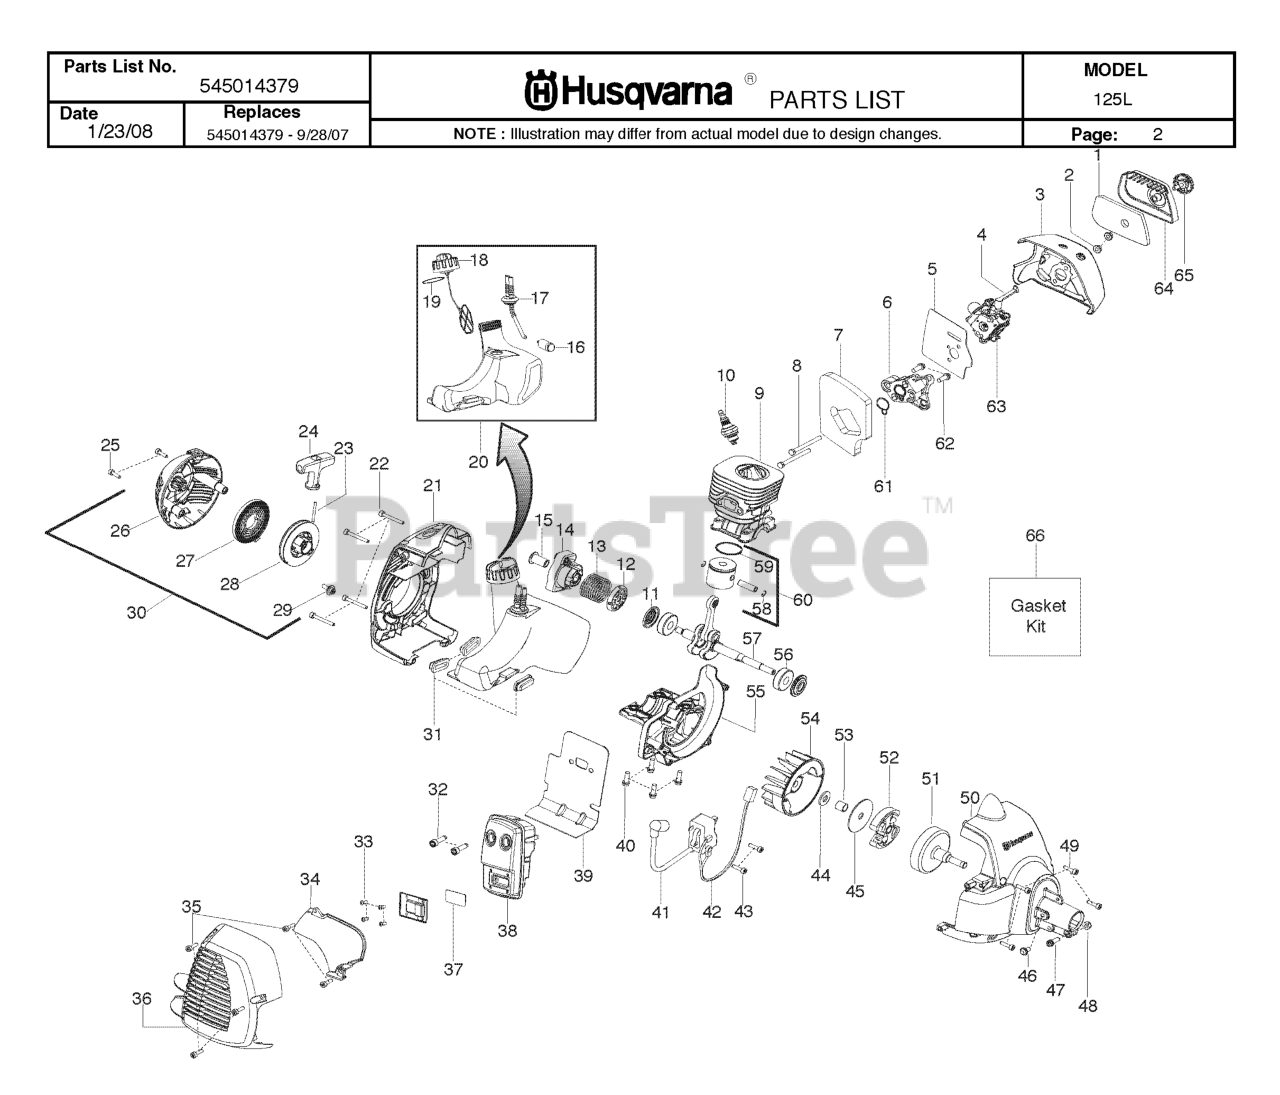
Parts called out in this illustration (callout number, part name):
1	FILTER AIRBOX
3	RP_AIR BOX
3	KIT-AIR BOX W/CABLE WIRE HARN
4	CHOKE LEVER
5	KIT GASKET CARB
6	CARB ADAPTOR
7	KIT GASKET 28CC TRIMMER
8	BOLT CARB ADAPTOR
9	CYLINDER
10	Plug - Spark (RCJ-8Y)
11	KIT SEAL CRANKSHAFT
12	WASHER STARTER
13	SPRING STARTER CUP
14	ASSY-STARTER CUP
15	COUPLING STARTER
16	FUEL PICK-UP ASSY
17	KIT FUEL LINE
18	ASSY-CAP W/RETAINER
19	O RING NITRILE
20	FUEL TANK ASSY
21	REAR SHROUD
24	STARTER HANDLE GRAY
25	SCREW M5-0.8X30MM
26	STARTER HOUSING
27	%KIT STARTER SPRING
28	KIT STARTER PULLEY
30	ASSY-STARTER HSG.
31	ISOLATOR FUEL TANK
32	BOLT MUFFLER
33	SCREW-10-16 X 1/2 HI-LO
34	SHIELD HEAT
35	SCREW M4 X 1.75 PT 16MM
36	GUARD-MUFFLER
37	KIT SPARK ARRESTOR SCREEN
38	ASSY-MUFFLER
39	GASKET PAPER METAL
40	SCREW-M5-0.8 X 25MM(TAP)
41	IGNITION MODULE MBU-7
42	ASSY MODULE LEAD WIRE
43	SCREW M4 X .70 TT 16MM
44	WASHER CLUTCH
45	WASHER-CLUTCH
48	LOCKNUT-HEX 10-24
49	SCREW M4 X .70 TT 16MM
50	FAN HSG ASSY
51	KIT, CLUTCH DRUM & FLEXSHAFT
51	ASSY-CLUTCH DRUM
52	%KIT CLUTCH ASSY
53	SPACER FLYWHEEL
55	CRANKCASE CASTING
56	BEARING RADIAL BALL (6201)
57	KIT CRANKSHAFT ASSY
58	WRIST PIN RET.
59	RING PISTON
60	KIT PISTON 28CC TRIMMER
61	KIT GASKET 28CC TRIMMER
62	SCREW-M5-0.8 X 25MM(TAP)
63	CARBURETOR
63	CARBURETOR KIT W38
64	COVER-AIR BOX
65	KNOB ASSY AIRBOX COVER
66	KIT GASKET 28CC TRIMMER
